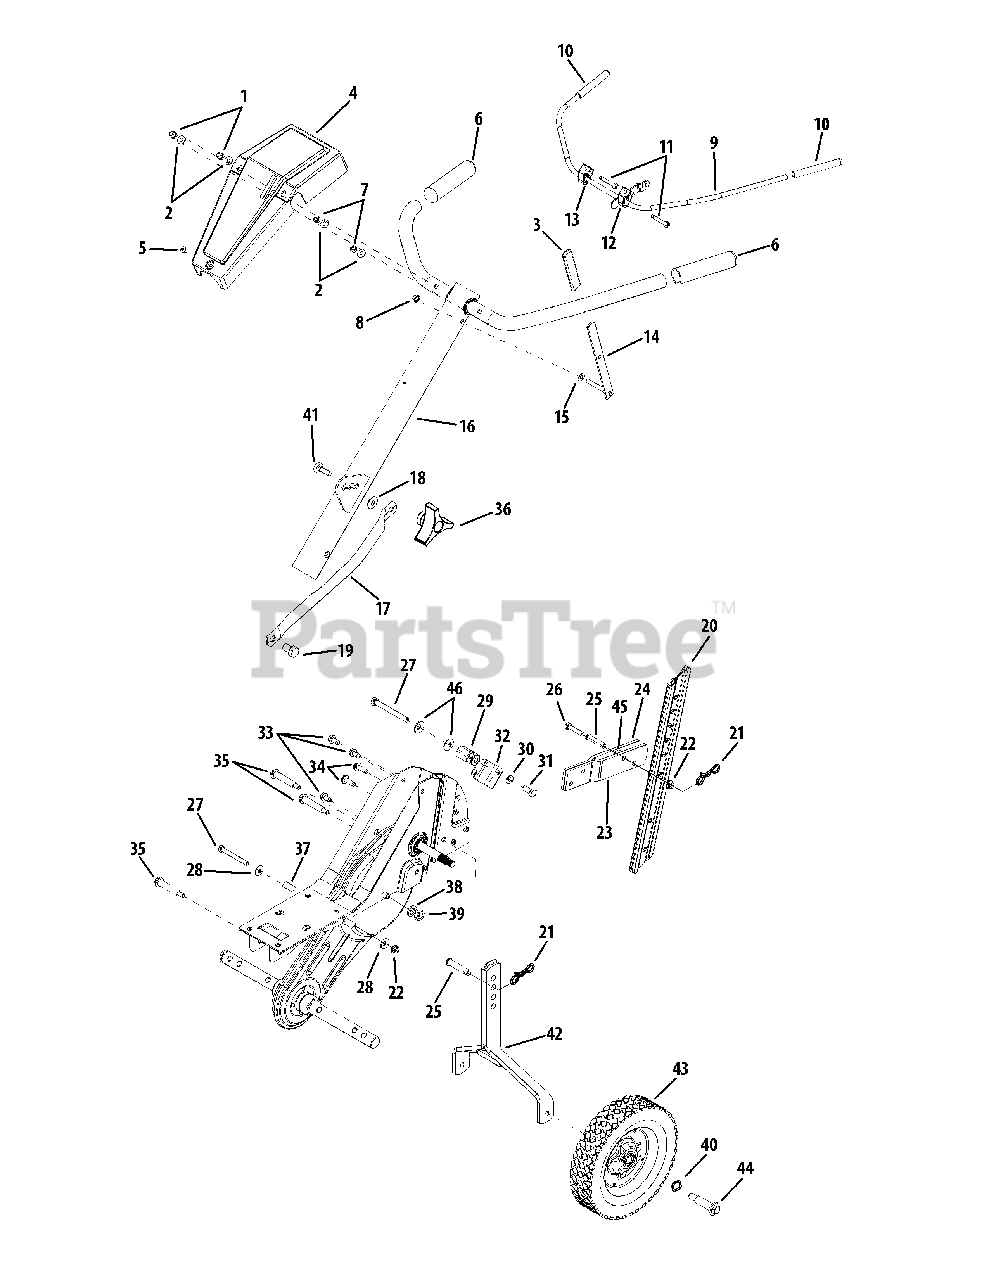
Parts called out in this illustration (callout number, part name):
1	Acorn Lock Nut, 1/4-20
2	Flat Washer, 271" x630"
3	Reverse Handle Grip
4	Handle Cover w/o throttle
5	Truss Machine Screw, #10 x 1/2"
6	Handle Grip
7	Hex Nut, 1/4-20
8	Cap Speed Nut
9	Clutch Handle Assembly
10	Clutch Grip
11	Hex Bolt, 1/4-20 x 225"
12	Clutch Handle Holder
13	Flat Washer, 406 x 875 x 059
14	Reverse Handle Assembly
15	Flat Washer, 344" x 62"
16	Handle Assembly Complete
17	Handle Brace
18	Bell Washer, 34"
19	Hex Bolt, 1/2-20
20	Depth Bar
21	Cotter Pin, Bow Tie
22	Hex Flange L-Nut, 5/16-18
23	Tail Piece Bracket, Left
24	Tail Piece Bracket, Right
25	Clevis Pin
26	Hex Bolt, 5/16-18 x 15"
27	Hex Bolt, 5/16-18 x 3"
28	Bell Washer, 340" x 872"
29	Hex Nut
30	L-Washer, 5/16"
31	Hex Bolt, 5/16-18
32	Cable Guide Bracket
33	Screw, :5/16-18 x 075
34	Hex Washer TT-Tap Screw
35	Shoulder Bolt, 5/16-18
36	Hand Knob
37	Spacer
38	Lock Washer, 7/16
39	Jam Nut, 7/16-20
40	Wave Washer 531 x 781 x 013
41	Carriage Bolt, 5/16-18 x 1
42	Wheel Hanger Bracket Assembly
43	Wheel, 8 x 175
44	Shoulder Screw, 496 x 1445
45	Spacer
46	Bell Washer, 340" x 872"
